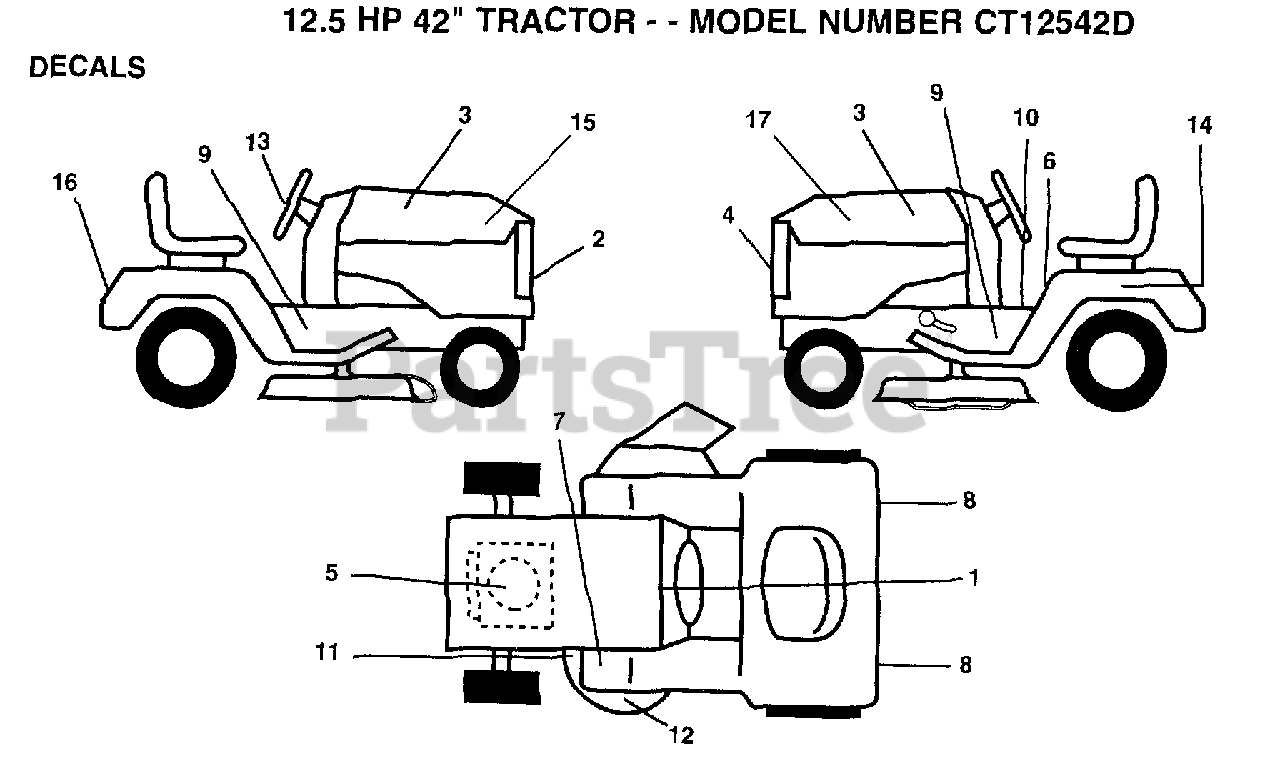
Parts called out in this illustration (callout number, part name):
1	DECAL.DASH.INST.
2	DECAL.GRILLE
3	"DECAL, HP HOOD"
6	DECAL
8	REFLECTOR-TAIL YT
9	CHASSIS DECAL
10	DECAL BRAK PARK
11	DECAL
13	DECAL INST STRWHL
14	DECAL
15	DECAL HD RH RALLY
16	DECAL.FENDER
17	DECAL HD LH RALLY
